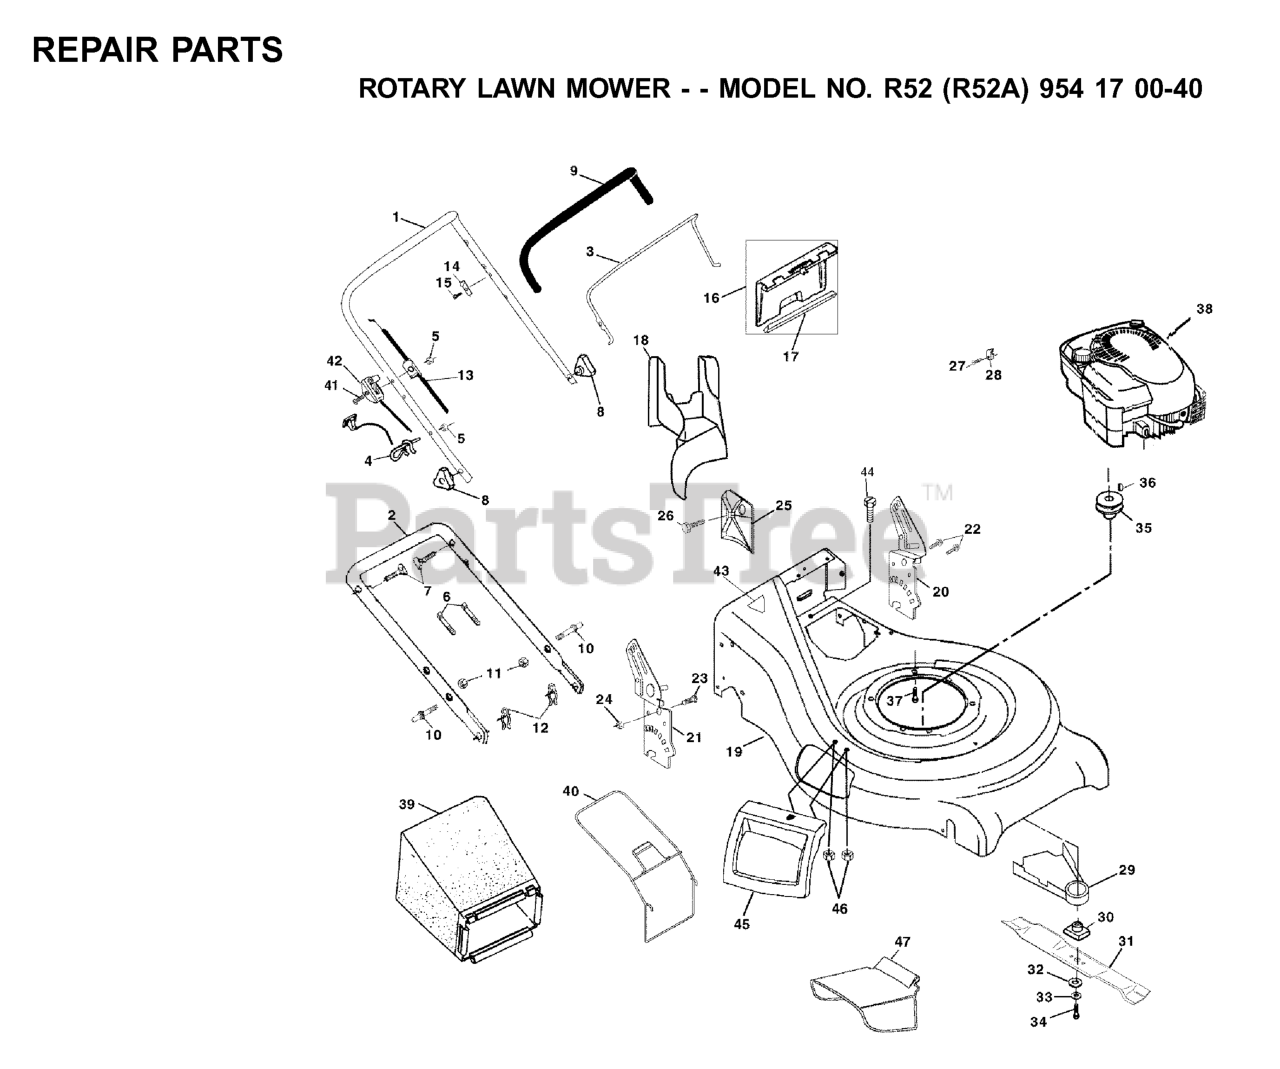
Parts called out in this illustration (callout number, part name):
1	HANDLE, UPPER DLX COMF. (GRIP)
2	HANDLE
3	CONTROL BAR
4	ROPE GUIDE
5	NUT
6	TIE GUIDE
7	HANDLE BOLT
9	GRIP.HANDLE.FOAM
10	BOLT
11	NUT
12	HAIRPIN COTTER
13	ENGINE ZONE CONTROL
14	BRACKET UPSTOP
15	SCREW.HEX.HEAD.WASHER.10-16
16	KIT.DOOR.REAR.21.WRAPPED.BLACK
17	SEALING
18	MULCH PLUG
20	.RACKET
21	RIGHT HANDLE BRKT. ASSM.
22	SELF-TAPPING SCREW 5/16-18X3/4
23	BOLT, HEX HEAD 5/16-18
24	LOCKNUT
25	CLIPPING DEFLECTOR
27	SCREW.HEX.HEAD.WASHER.10-16
28	CABLE CLAMP(ENGINE)
29	DEBRIS SHIELD
30	BLADE ADAPTOR
31	21" MULCH BLADE PREMIUM
32	WASHER,HARDEN
33	LOCKWASHER
34	SCREW, HEX HD 3/8-24 X 1-3/8
35	ENGINE.PULLEY.FWG
36	HI PRO KEY PM WSL
37	BOLT 3/8-16X1-1/8
40	FRAME.GRASS.CATCHER.WALK.21"
41	SCREW 1/4-20 X 2.12
42	THROTTLE TRIGGER
43	DECAL MOWER CUT/FINGER
45	MULCH COVER
47	DEFLECTOR.21.MCUT.RWGD.GRAY
